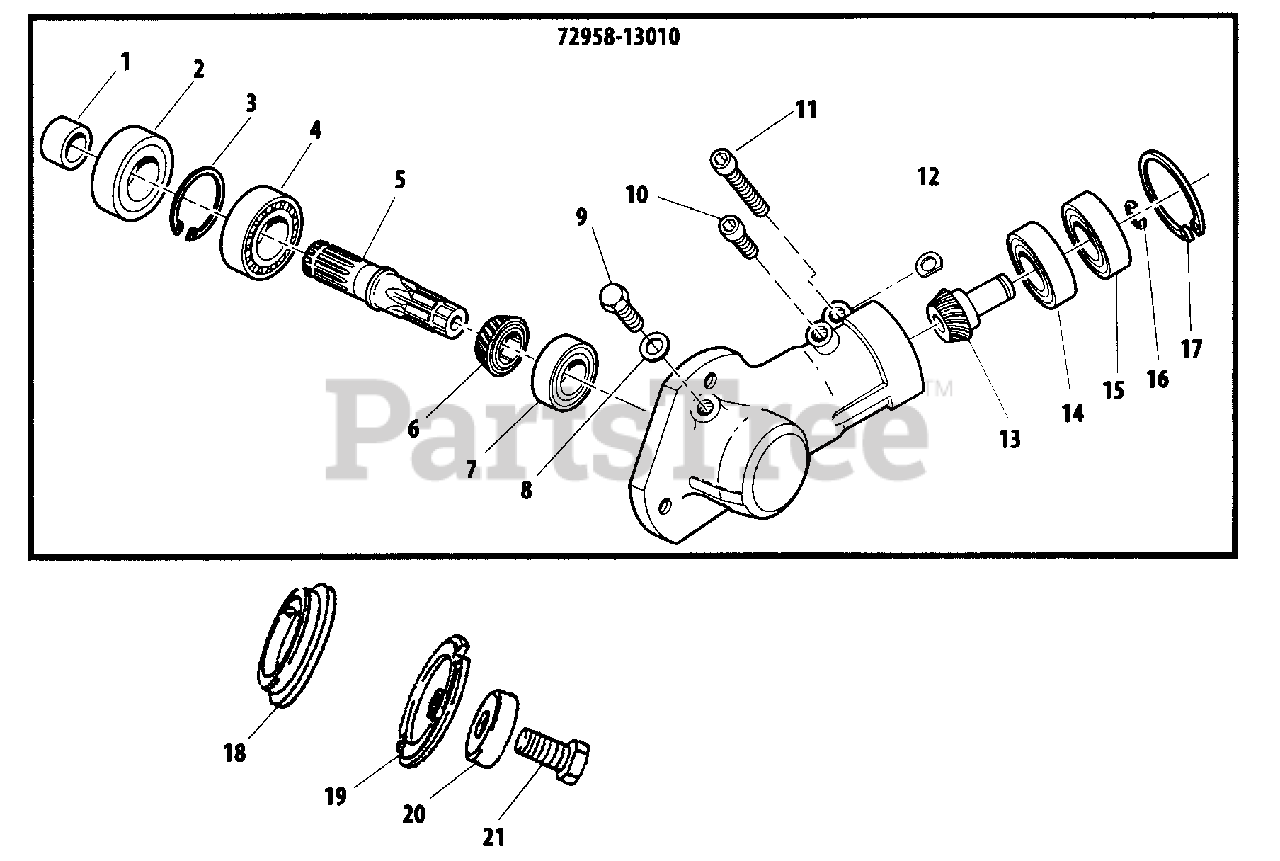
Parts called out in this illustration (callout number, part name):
1	SPACER
2	SEAL, OIL
3	RING, SNAP Ø28
4	BEARING, BALL 6001
5	SHAFT, GEAR
6	GEAR, BEVEL
7	BEARING, BALL 608 DDU
8	WASHER 6.5×11.5×0.8
9	BOLT M6×10
10	BOLT M5×16
11	BOLT M5×25
12	D-WASHER
13	GEAR, SHAFT
14	BEARING, BALL 609
15	BEARING, BALL 609ZZ
16	RING, SNAP
17	RING, SNAP Ø24
18	PLATE, ADAPTOR - UPPER
19	PLATE, ADAPTOR - LOWER
20	GUARD, BOLT
21	BOLT 8
72958-13010	GEAR CASE ASSY
